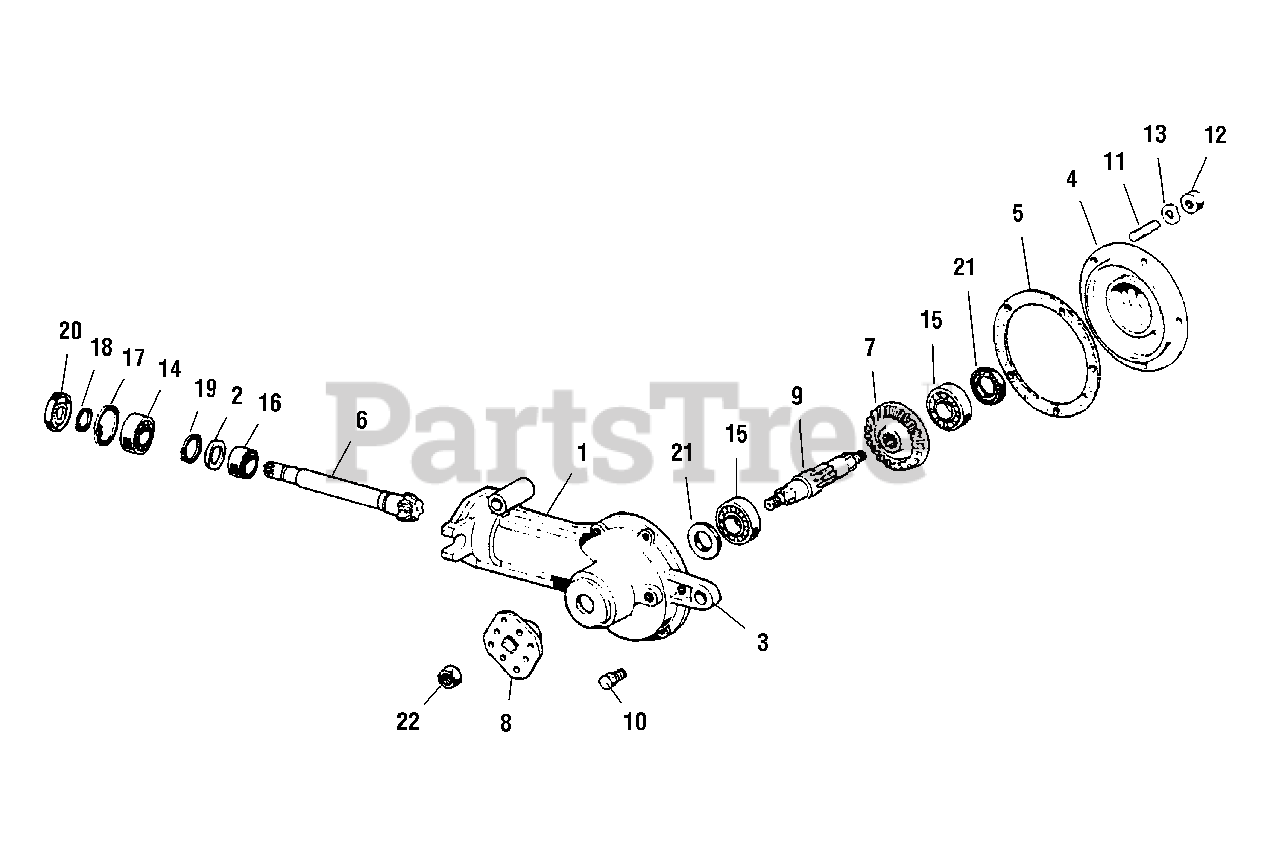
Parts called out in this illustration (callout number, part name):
1	TILLER DRIVE TRANSMISSION
4	COVER-Casting
10	PLUG-Pipe, 1/4", Oil Level Drain
11	STUD, 8mm x 20mm
12	NUT, 8mm x 1.25mm
13	WASHER-Wavy, 8mm
14	BEARING-Pinion, 20mm x 47mm x 14mm
15	BEARING-Tine Axle, 25mm x 62mm x 17mm
16	BEARING-Needle, 25mm x 38mm x 20mm
17	SNAP RING, 47 I
18	SNAP RING, 20 E
19	SNAP RING, 25 E
20	SEAL-Pinion, 20mm x 47mm x 7mm
21	SEAL-Tine Axle, (Wheel Shaft), 25mm x 52mm x 8mm
22	NUT, 20mm x 1.50mm
